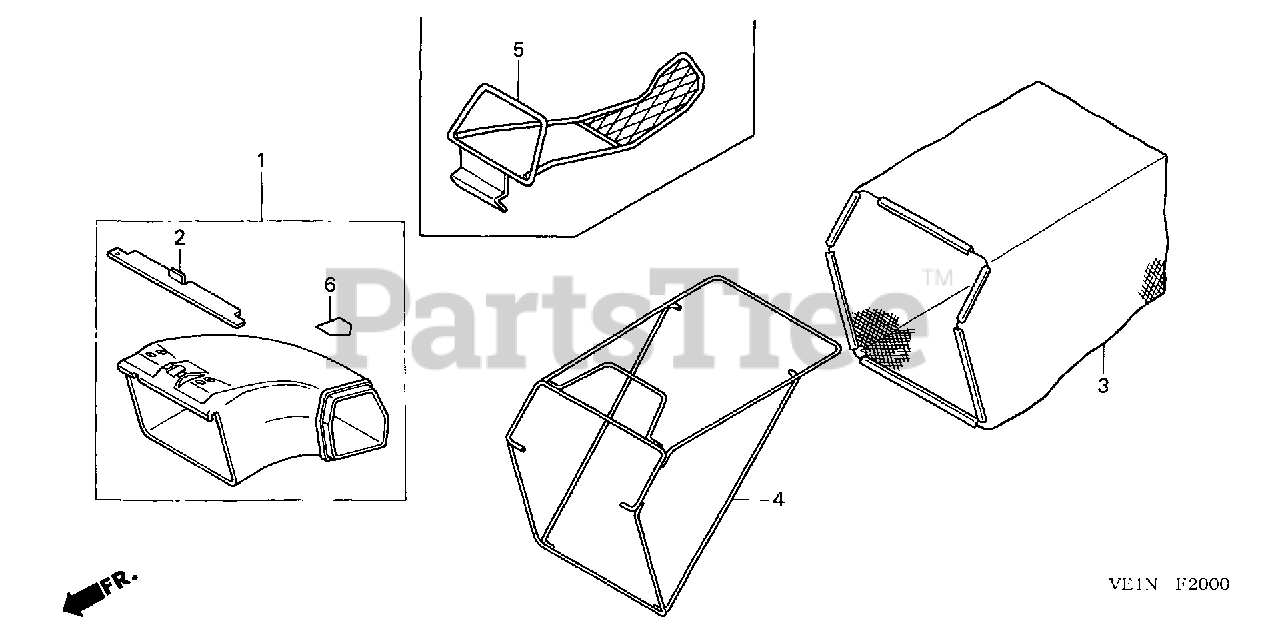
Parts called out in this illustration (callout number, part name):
1	CHUTE KIT, SIDE DISCHARGE
2	BRACKET, MOUNTING (NOT AVAILABLE)
3	FABRIC, GRASS BAG
4	FRAME, BAG
5	SHREDDER, LEAF
6	LABEL B, HOUSING CAUTION (ENGLISH)
